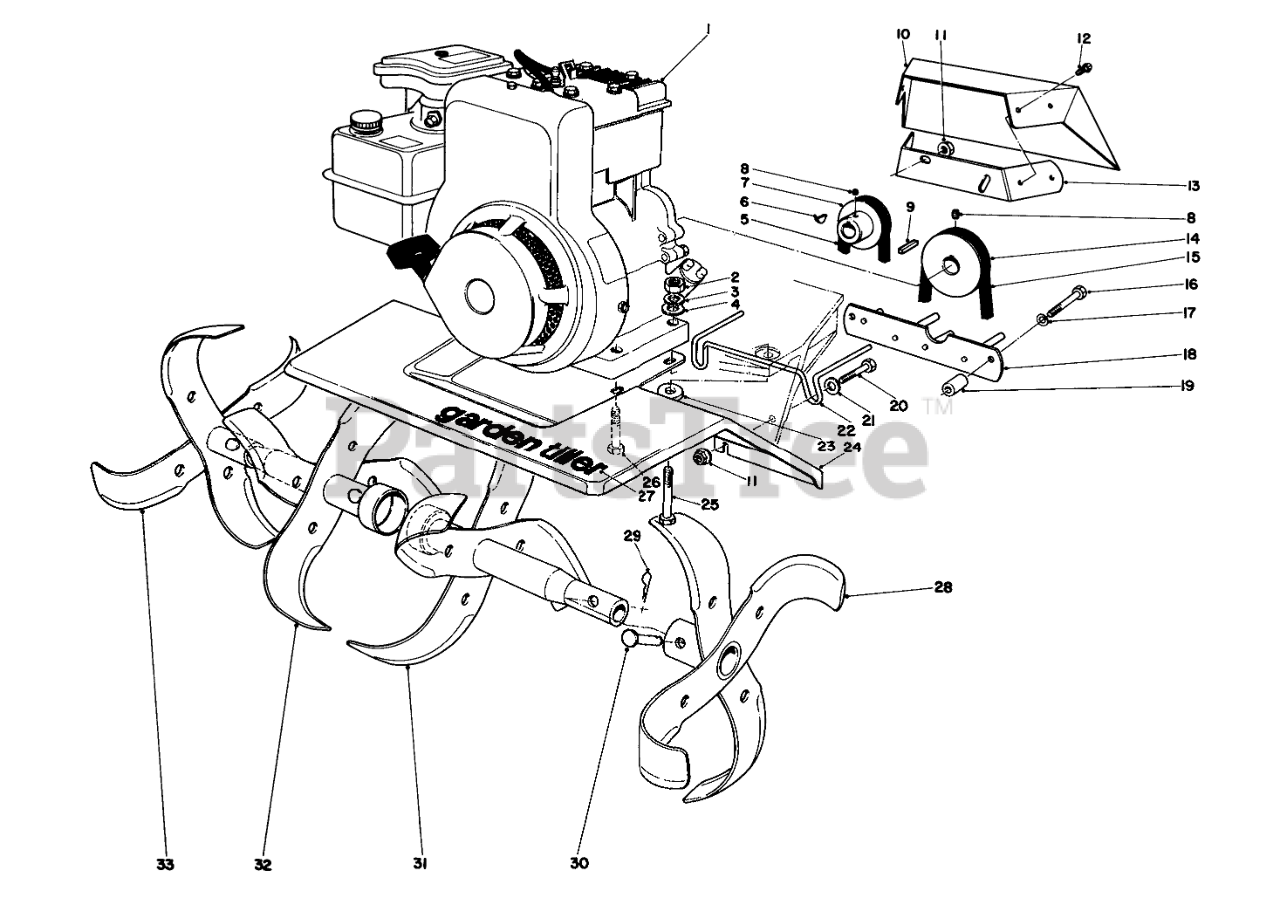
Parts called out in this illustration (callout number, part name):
1	Engine
2	NUT-HEX
3	WASHER-LOCK
4	WASHER-PLAIN
5	V-BELT
6	HI PRO KEY
7	Pulley-Engine Rev.
8	SCREW-HSH
9	KEY-SQUARE
10	PULLEY GUARD
11	NUT-LOCK, HHF
12	SCREW-HWHTF
13	Strap-Belt Shield
14	ENGINE PULLEY
15	V-BELT
16	SCREW-HH
17	WASHER-LOCK
18	Belt Guide
19	Spacer
20	SCREW-HH
21	WASHER-FLAT
22	BELT GUIDE
23	WASHER-FLAT
24	TINE SHROUD
25	SCREW-HH
26	SCREW-HH
27	Decal
28	LH OUT SLASH TINE WA
29	PIN-COTTER
30	TINE PIN
31	Inner Tine L.H.
32	Inner Tine R.H.
33	RH OUT SLASH TINE EA
